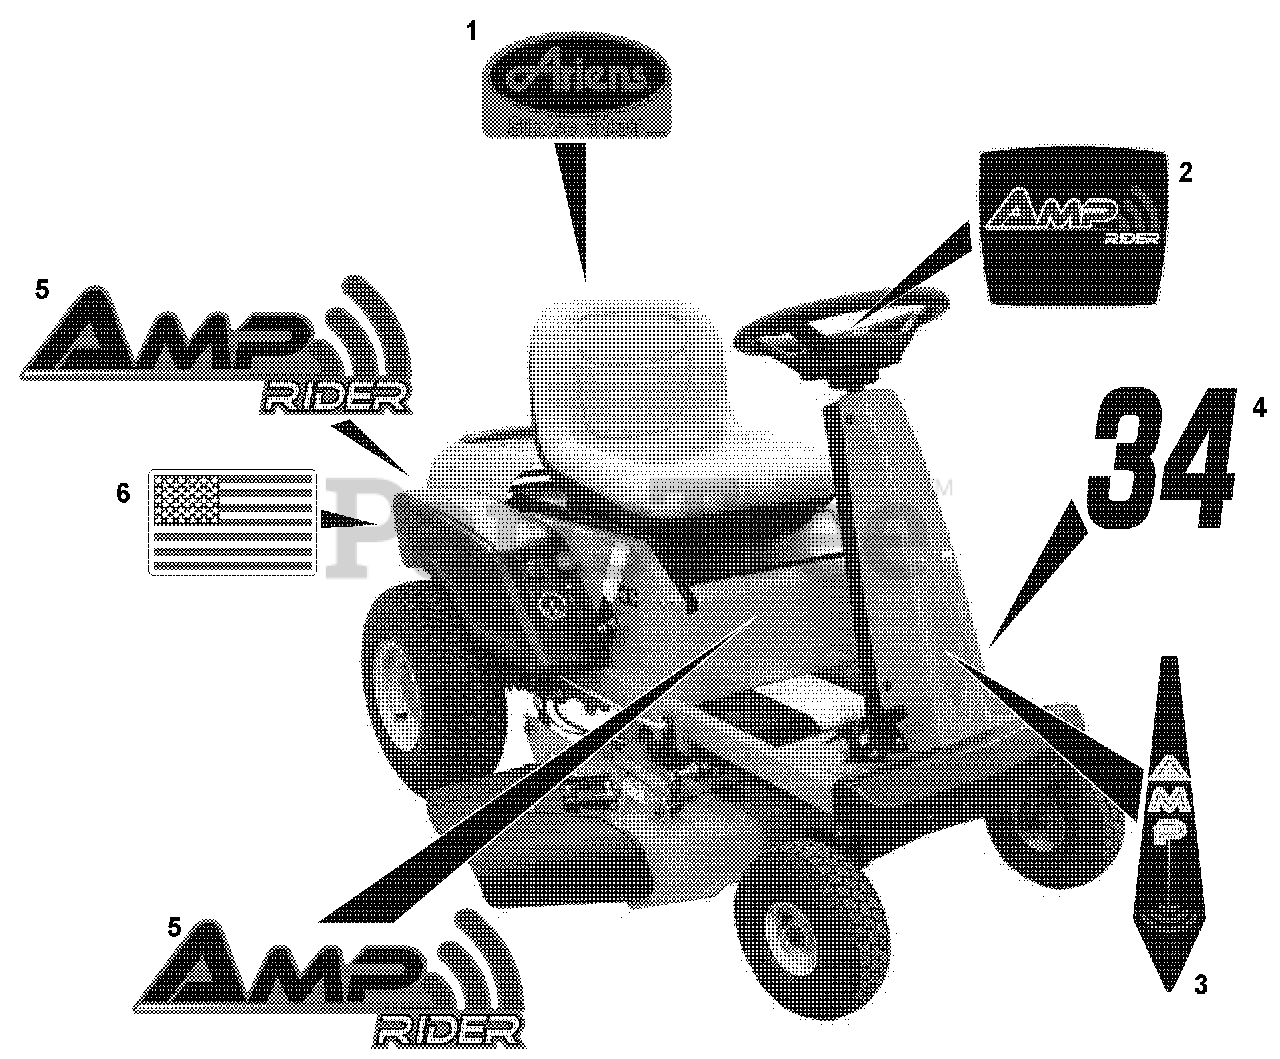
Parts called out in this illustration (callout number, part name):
1	DECAL, ARIENS SINCE 1933 SM
2	STEERING WHEEL GRAPHICS, AMP
3	FRONT TOWER GRAPHICS, AMP
4	DECAL, DECK SIZE, 34"
5	KICKPLATE GRAPHICS, AMP
6	DECAL, AMERICAN FLAG
